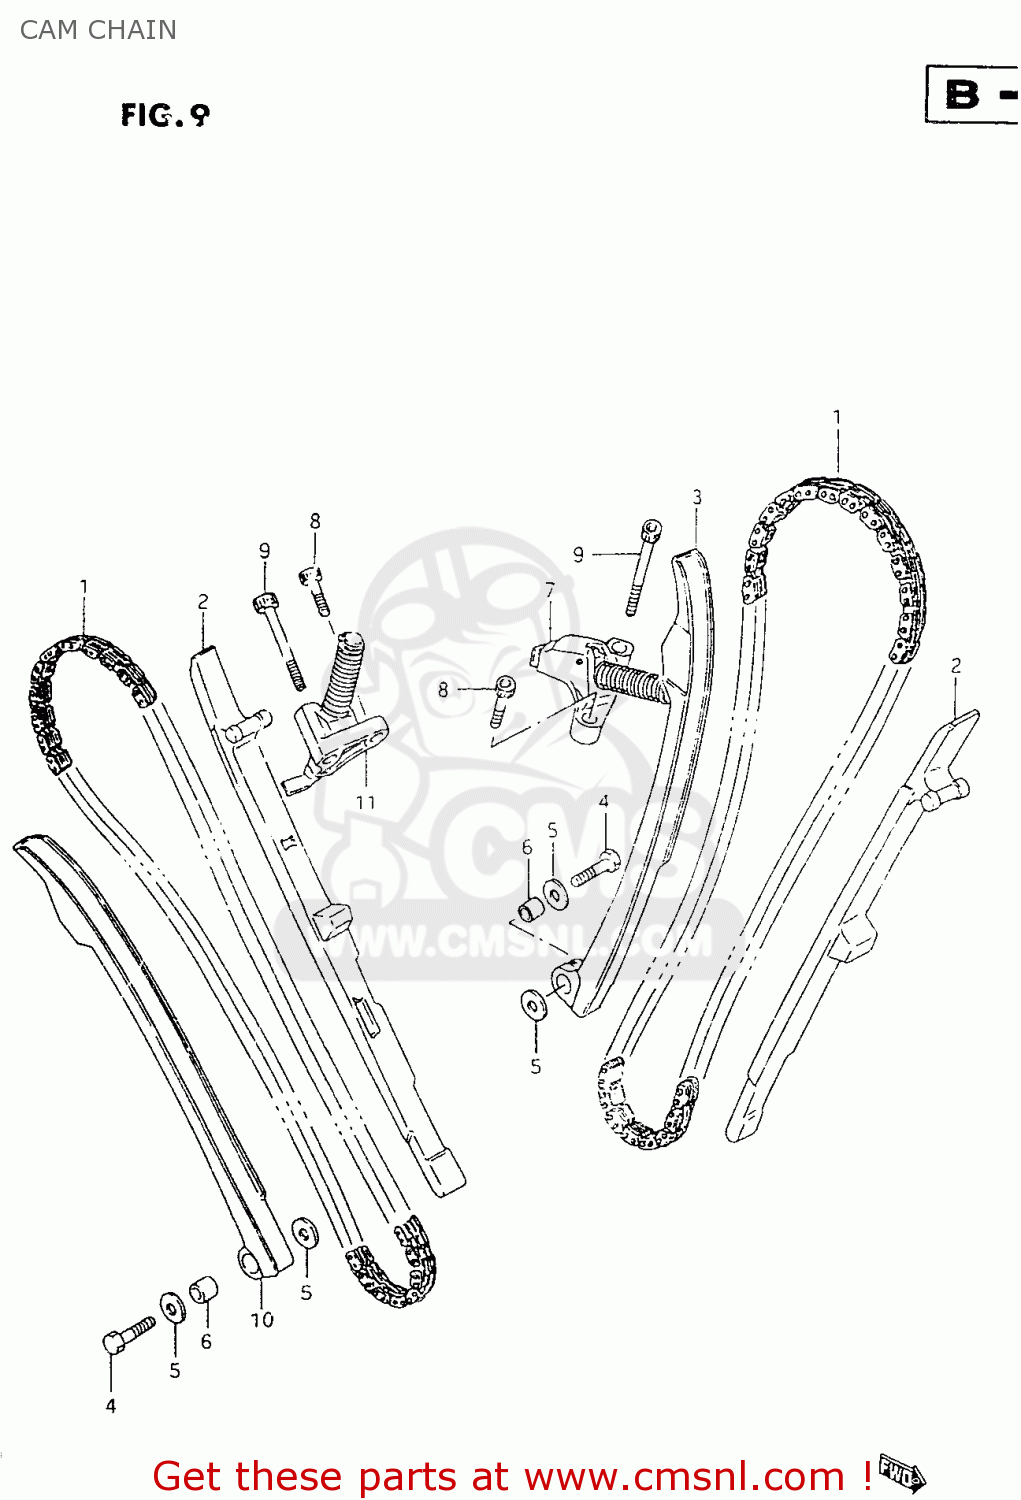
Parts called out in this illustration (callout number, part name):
1	CHAIN,CAMSHAFT DRIVE
2	GUIDE,CAM CHAIN
3	TENSIONER,FR CAM CHAIN
4	BOLT(6X26)
5	WASHER
6	SPACER(6X11X11)
7	ADJUSTER ASSEMBLY,FRONT TENSIONER
8	BOLT,CRKCASE,R
9	BOLT
10	TENSIONER,RR CAM CHAIN
11	ADJUSTER ASSEMBLY,REAR TENSIONER
